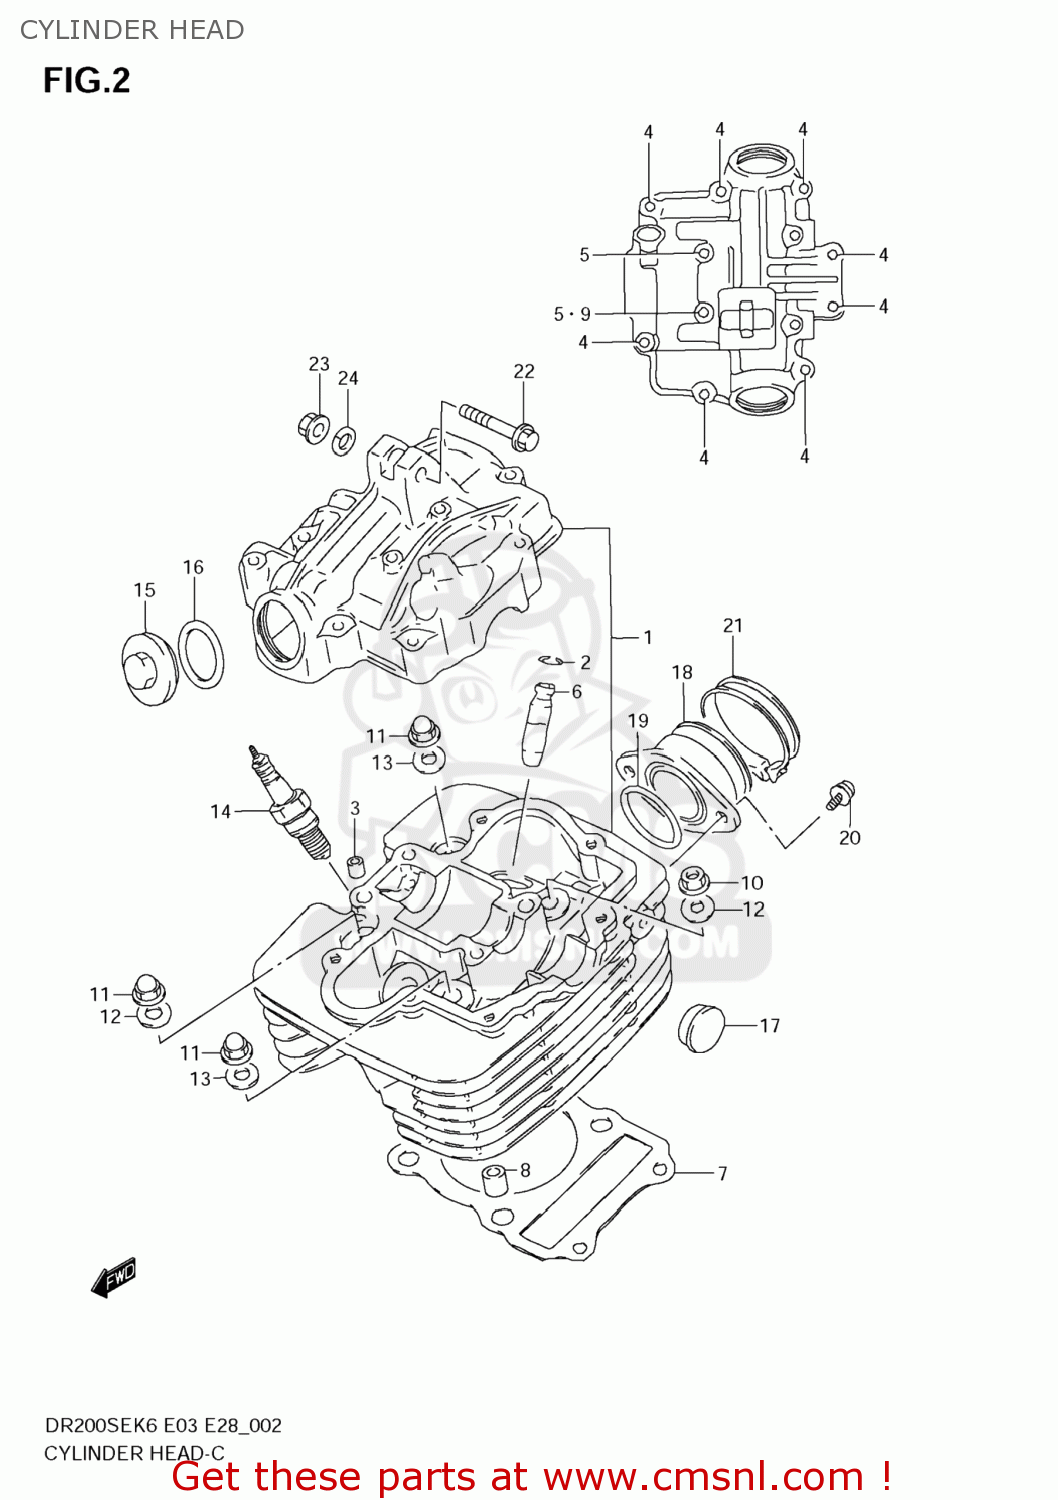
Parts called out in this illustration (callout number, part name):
1	HEAD ASSY,CYLINDER
2	RING,SNAP
3	PIN(6.2X8X11)
4	BOLT
5	BOLT
6	GUIDE,VALVE
7	GASKET,CYLINDER HEAD (NAS)
8	PIN
9	GASKET(5.8X13X1.2) (NAS)
10	NUT
11	NUT
12	WASHER(8.5X19X2.3)
13	GASKET(8.5X17X2.3) (NAS)
14	PLUG,SPARK(DR8EA)
15	CAP,INSPECTION
16	O RING(D:3,ID:29.5)
17	PLUG(OD:22.5)
18	PIPE,INTAKE
19	O RING(D:1.9,ID:34.6)
20	SCREW
21	CLAMP
22	BOLT(8X53)
23	NUT
24	WASHER,LOCK
